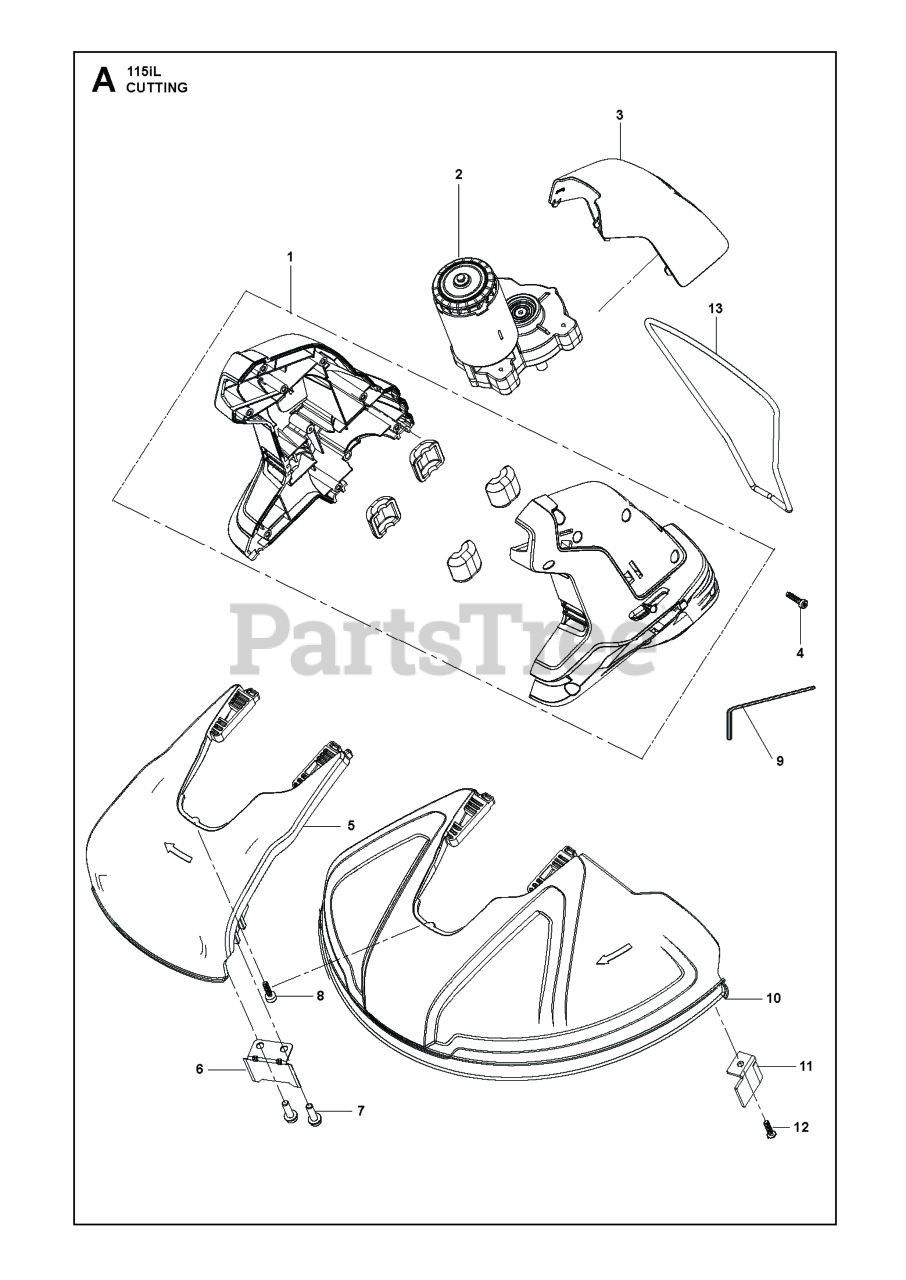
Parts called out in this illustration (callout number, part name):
2	GEARBOX ASSY 115IL TRIMMER
2	GEARBOX ASSY 36V
3	COVER MOTOR HOUSING
4	SCREW ST4X16
5	GUARD FOR CUTTING HEAD 36V
6	BLADE LINE CUTTER
7	SCREW
8	SCREW ST4*16
10	GUARD FOR CUTTING HEAD
11	BLADE 330MM
12	SCREW ST4X16
13	RING PLANT GUARD
